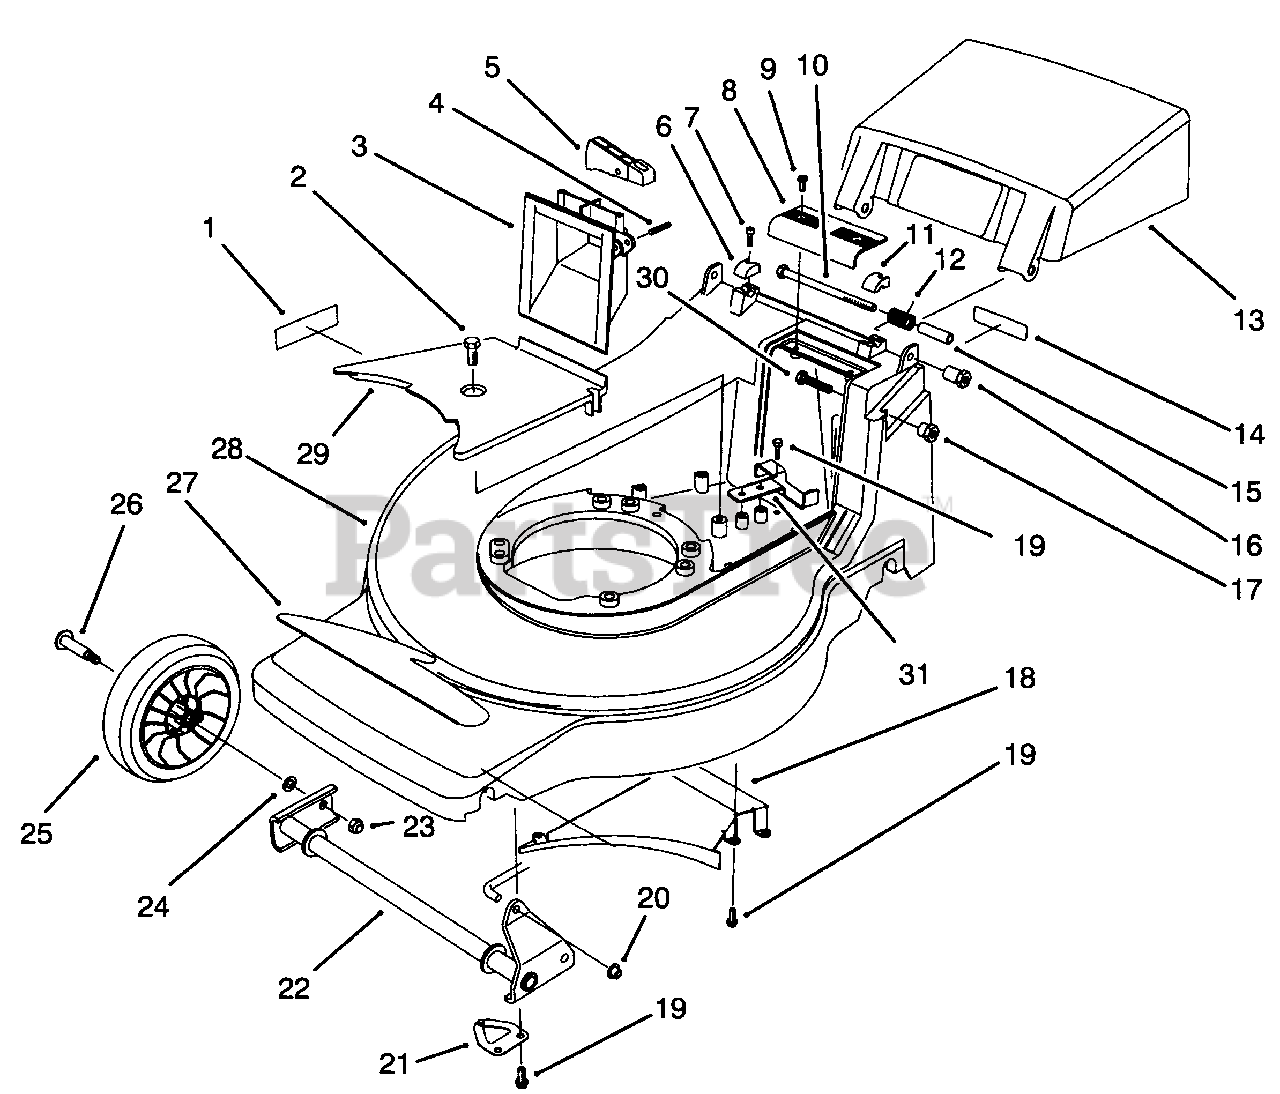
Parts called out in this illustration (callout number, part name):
1	Decal-DIN
2	Screw-Tapping
3	Grip-Lower
4	Pin-Groove
5	Trigger-HOC
6	Cap-R.H. Hinge Bolt
7	Screw-Thread Forming
8	Grip-Upper
9	Screw-Pan Hd. Phillips
10	Screw-Hex Hd. Cap
11	Cap-L.H. Hinge Bolt
12	Spring-Door
13	Door-Discharge
14	Decal-French Regulation
15	Spacer-Door
16	Spacer-Handle
17	Spacer-Handle
18	Ramp-Discharge
19	Screw-Tapping
20	Nut-Push
21	Retainer-Shaft
22	Pivot-Front
23	Nut-Lock
25	Wheel & Tire Assembly
26	Bolt-Wheel
27	Decal-Deck 400XS
28	Housing (Incl. Ref. #1)
29	Cover-Belt
30	Screw-Hex Hd. Cap
31	Guide-Rear Belt
